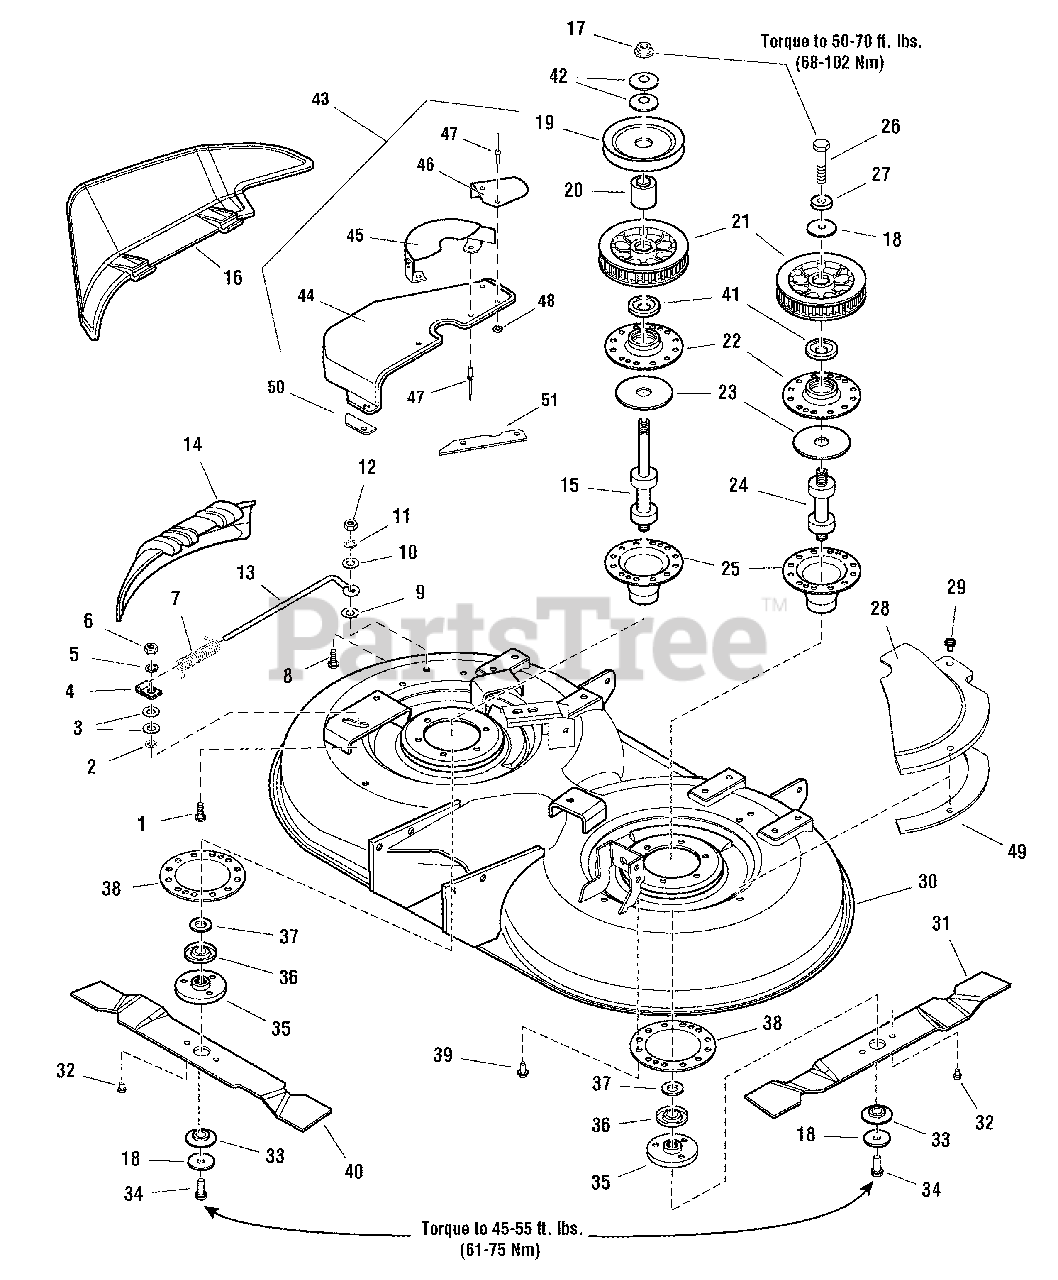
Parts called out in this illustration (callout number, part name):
1	CARRIAGE BOLT,1/4-20 x 7/8, Black
2	NUT, Push, 1/4, Black
3	WASHER, 1/4, Black
4	CLAMP, Wire, Black
5	LOCKWASHER, 1/4, Black
6	NUT, Hex, 1/4-10, Black
7	SPRING, Torsion, Black
8	CARRIAGE BOLT, 5/16-18 x 1, Black
9	NUT, Push, 5/16, Black
10	WASHER, 5/16, Black
11	LOCKWASHER, 5/16, Black
12	NUT, Hex, 5/16, Black
14	DOOR, Mulching
15	ARBOR SHAFT & BEARING ASSEMBLY
16	DEFLECTOR, Discharge
17	NUT, Hex Flange, 9/16-18
18	WASHER, Spring, 7/16, Black
19	PULLEY, 5" OD x 1" ID
21	SPROCKET & FLANGE ASSEMBLY, 38 Tooth, w/Screws
22	HOUSING, Arbor, Top
23	GASKET, Foam
24	ARBOR SHAFT & BEARINGS ASSEMBLY
25	HOUSING, Arbor, Bottom, w/Lube Fitting
26	CAPSCREW, Hex Head, 7/16-14 x 2-3/4, GR 8, Black
27	WASHER, 7/16, Black
28	COVER, Arbor, LH, Black
29	CAPSCREW, Hex Washer Head, Tap Tite, 5/16-18 x 3/4, Black
30	HOUSING ASSEMBLY
31	BLADE, Mower, 20-3/8, LH
33	WASHER, Spline
34	CAPSCREW, Hex Head, 7/16-14 x 1-1/4, GR 8
35	ADAPTER, Blade
36	SHIELD, Bearing
37	WASHER, Shim, Black
38	ADAPTER, Arbor
39	CAPSCREW, Hex Head, 5/16-18 x 1, Black
40	BLADE, Mower, 20-3/8, RH
41	SHIELD, Bearing Upper, Arbor
42	WASHER, Bellville
43	COVER ASSEMBLY, Arbor, RH (Includes Ref. Nos. 43 thru 48)
44	COVER, Arbor RH
45	GUARD ASSEMBLY, RH
46	GUARD, Extension
48	WASHER, 3/16 x 3/4 x 1/16
49	SHIM-Cover LH 7GA 40" Mowers
50	SHIM-Cover RH 7GA 2.8 LG 40" Mowers
51	SHIM-Cover RH 7GA 6.5 LG 40" Mowers
